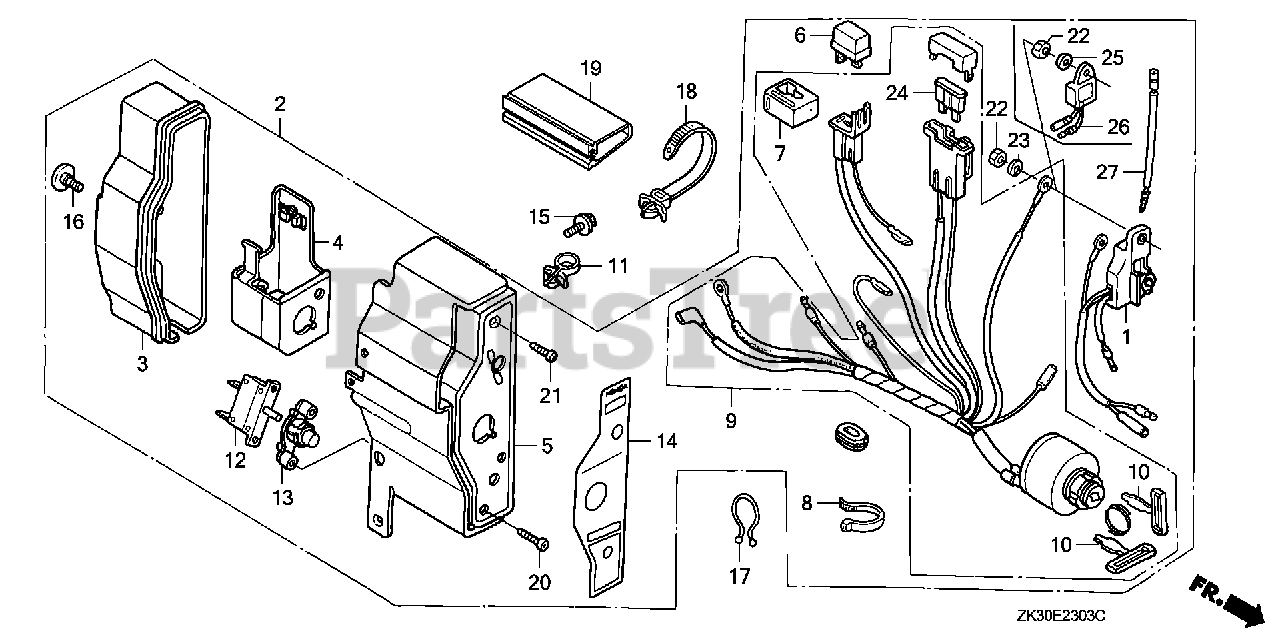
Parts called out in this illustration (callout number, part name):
1	ALERT UNIT, OIL (SEL) (NOT AVAILABLE)
2	BOX ASSY., CONTROL *R8* (ALERT) (BRIGHT RED) (NOT AVAILABLE)
2	BOX ASSY., CONTROL *T39* (ALERT) (GEKO BLUE)
2	BOX ASSY., CONTROL *NH105* (ALERT) (MAT BLACK)
2	BOX ASSY., CONTROL *R280* (ALERT) (POWER RED)
3	CASE, CONTROL
4	BRACKET, CASE MOUNTING
5	PANEL, CONTROL *R8* (BRIGHT RED)
5	PANEL, CONTROL *T39* (GEKO BLUE)
5	PANEL, CONTROL *NH105* (MAT BLACK)
5	PANEL, CONTROL *R280* (POWER RED)
6	RECTIFIER ASSY., SILICON (SHINDENGEN)
7	SUSPENSION, CONNECTOR
9	SWITCH ASSY., COMBINATION
10	KEY (HONDALOCK)
11	HOLDER, STOP SWITCH WIRE
12	PROTECTOR, CIRCUIT (1.0A)
13	LENS ASSY., PROTECTOR
14	MARK, CONTROL BOX (EXP)
14	PANEL, CONTROL BOX (EXTERNAL-ALERT) (NOT AVAILABLE)
15	BOLT, FLANGE (6X12) (CT200)
16	SCREW, SPECIAL (6X12)
17	CLIP, PURSE LOCK
18	STRAP, CABLE (118MM) (BLACK)
19	TUBE, FASTENER (30MM)
20	SCREW, PAN (3X12)
21	SCREW, PAN (4X12)
22	NUT, HEX. (4MM)
23	WASHER, SPRING (4MM)
24	FUSE, BLADE (5A)
25	WASHER, PLAIN (4MM)
26	ALERT UNIT, OIL
27	SUB-WIRE HARNESS
